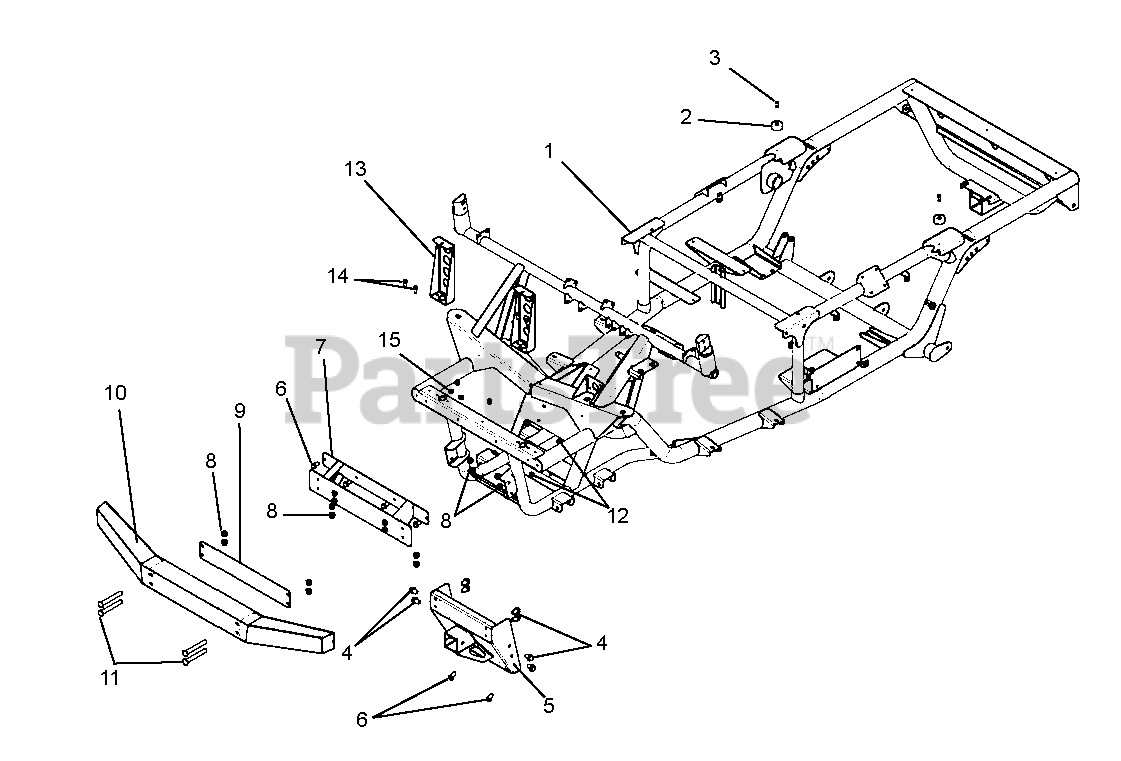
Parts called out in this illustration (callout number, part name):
1	WELDMENT, MAINFRAME
2	BUMPER, RUBBER .625 X 1.50 DIA
3	RIVET, 3/16 X .500 POP
4	HFSS 3/8-16 X 3/4 LG
5	WELDMENT, RECEIVER, FRONT
6	BOLT, SERRATED HEX FLANGE HEAD .312-18 X .75
7	WELDMENT, MNT, BUMPER
8	NUT, SPIN, LOCK FLANGE .375-16
9	PLATE, BACK BUMPER, RED (996123, 125, 146)
10	WELDMENT, BUMPER
11	BOLT, ROUNDHEAD SQUARE NECK .38-16 X 4.0 G5 YWZC
12	NUT, SPIN LOCK FLANGE .312-18
13	HOOD MOUNT BRACKET
14	BOLT, HEX .25-20 X .75 GR5 YWZC
15	NUT, LOCKING FLANGE .25-20 TWZC
